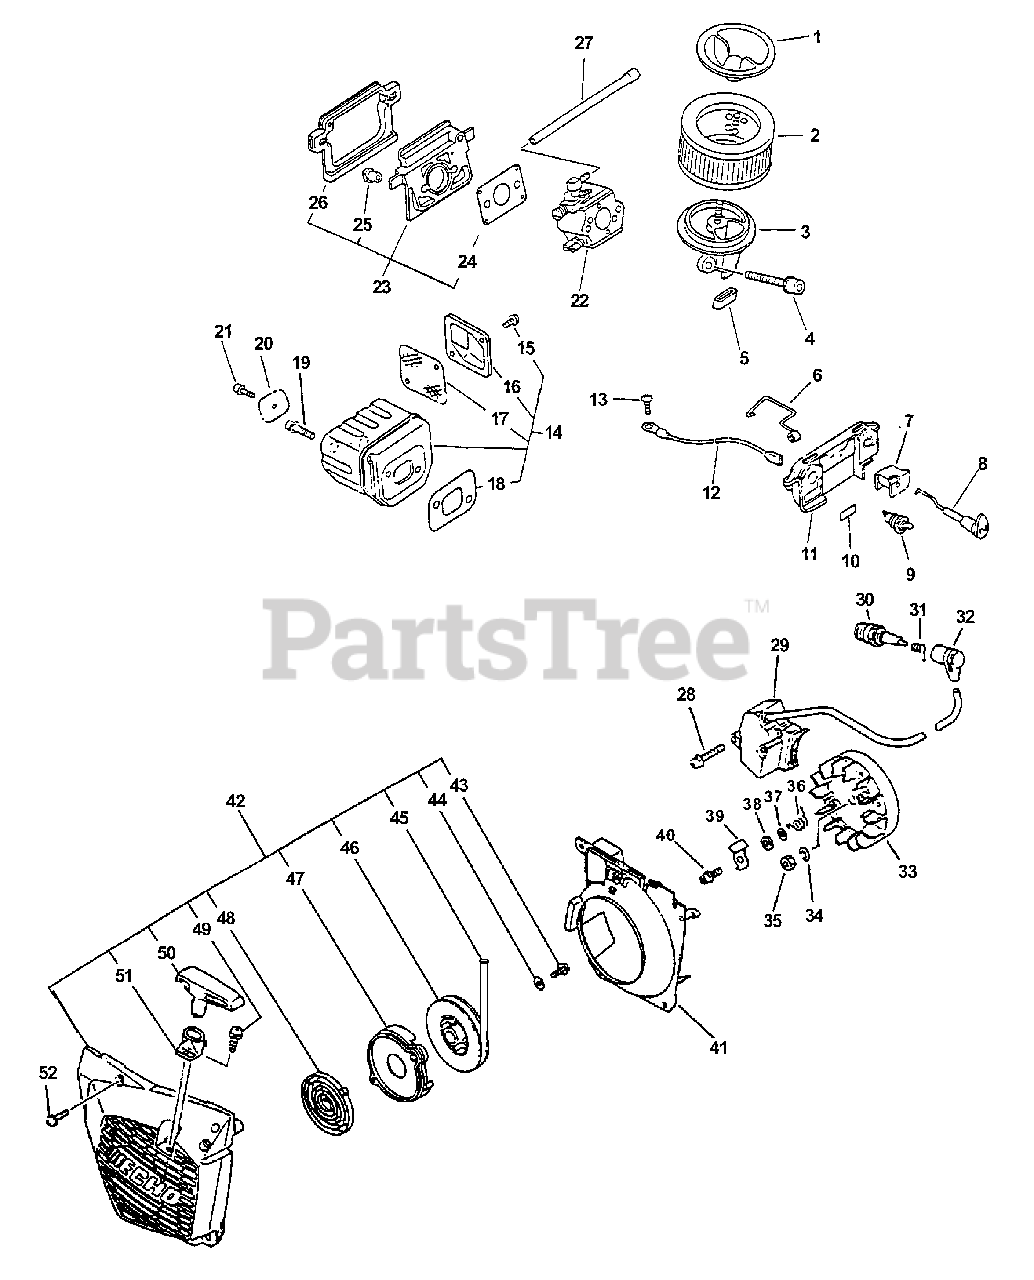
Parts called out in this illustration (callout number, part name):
1	COVER, AIR FILTER
2	FILTER, AIR
3	MOUNT, AIR FILTER
4	SCREW - 5X50
6	ROD, THROTTLE
8	ROD, CHOKE
9	IGNITION SWITCH ASSY
10	LABEL - STOP
11	BRACKET, SWITCH
12	LEAD - GROUND
13	SCREW - 4X6
14	MUFFLER ASSY
15	SCREW - 4X8
16	GUIDE, EXHAUST
17	SCREEN, SPARK ARRESTOR
18	GASKET, EXHAUST
19	SCREW - 5X14
20	PLATE
21	SCREW - 4X6
22	CARBURETOR WT-416
23	INSULATOR KIT
24	GASKET, INTAKE
26	CUSHION
27	PIPE - IMPULSE
28	SCREW - 4X30
29	COIL, IGNITION
30	SPARK PLUG -- CJ-6Y
31	TERMINAL, SPARK PLUG CAP
32	CAP, SPARK PLUG
33	FLYWHEEL
34	LOCKWASHER - 8
36	SPRING, RETURN
37	WASHER - 5
39	PAWL, STARTER
40	SCREW - 5X14
41	SHIELD, FAN
42	STARTER ASSY
43	SCREW - 5X12
44	WASHER - 5
45	ROPE, STARTER - 3.5X1000
46	REEL, ROPE
47	PLATE, STARTER
48	SPRING, REWIND
49	SCREW - 3X14
50	GRIP, STARTER
51	GUIDE, ROPE
52	SCREW - 5X18
